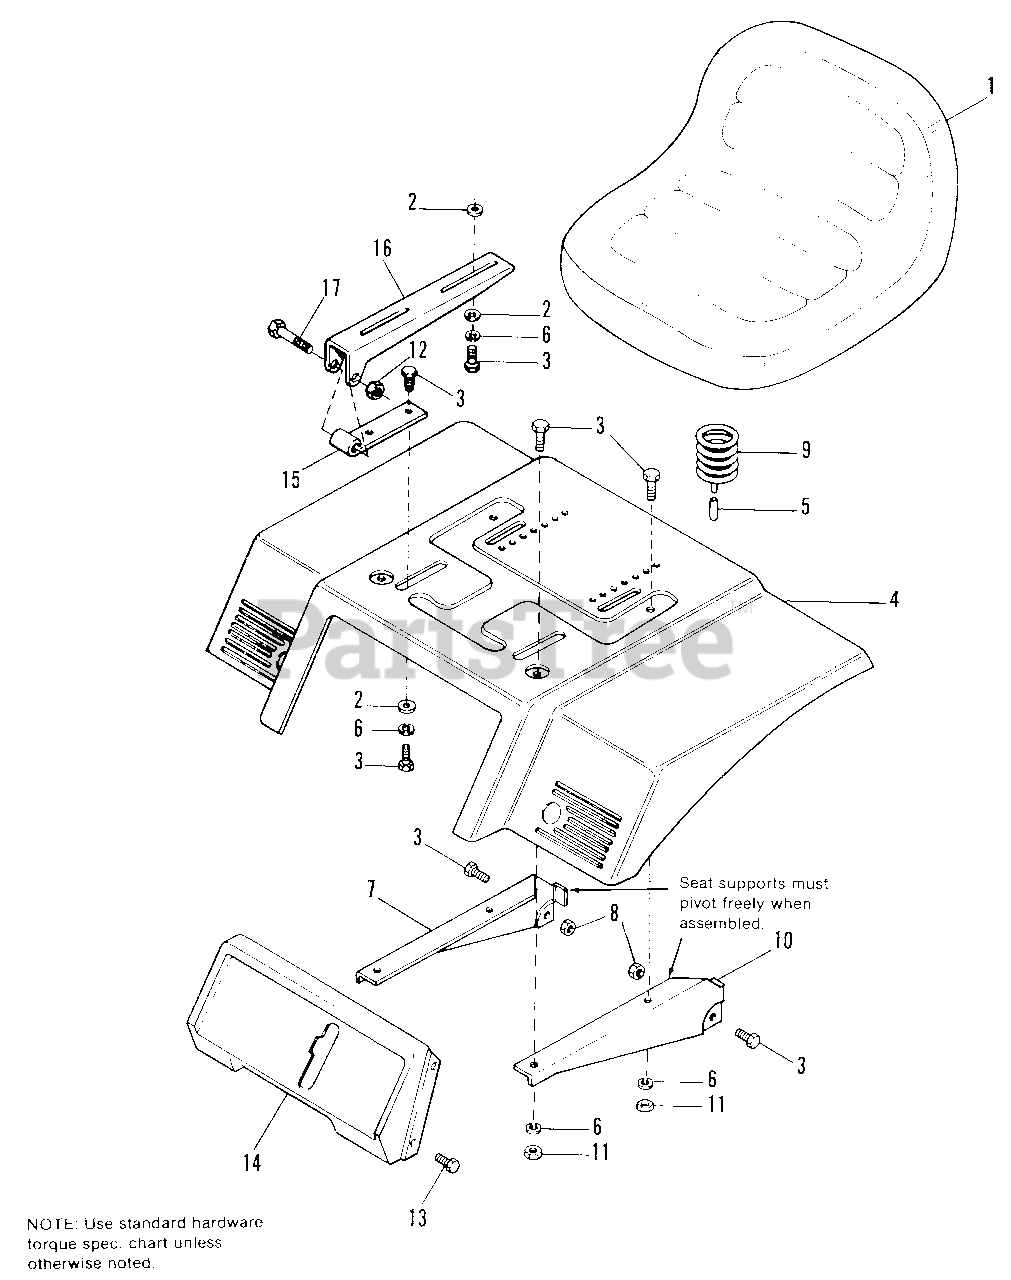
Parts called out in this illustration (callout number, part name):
2	WASHER, Plain, 5/16
3	CAPSCREW, Hex, 5/16-18 x 3/4
4	DECK, Seat
5	COVER, Wire
6	LOCKWASHER, 5/16
7	SUPPORT, Seat, R.H.
8	LOCKNUT, Hex, 5/16-18
9	SPRING, Seat
10	SUPPORT, Seat, L.H.
11	NUT, Hex, Full, 5/16-18
12	LOCKNUT, Hex, 3/8-16
13	SCREW, Hex, Taptite, 1/4-20 x 1/2
14	PANEL, Shift
15	HINGE, Lower
16	HINGE, Upper
17	CAPSCREW, Hex, 3/8-16 x 2
